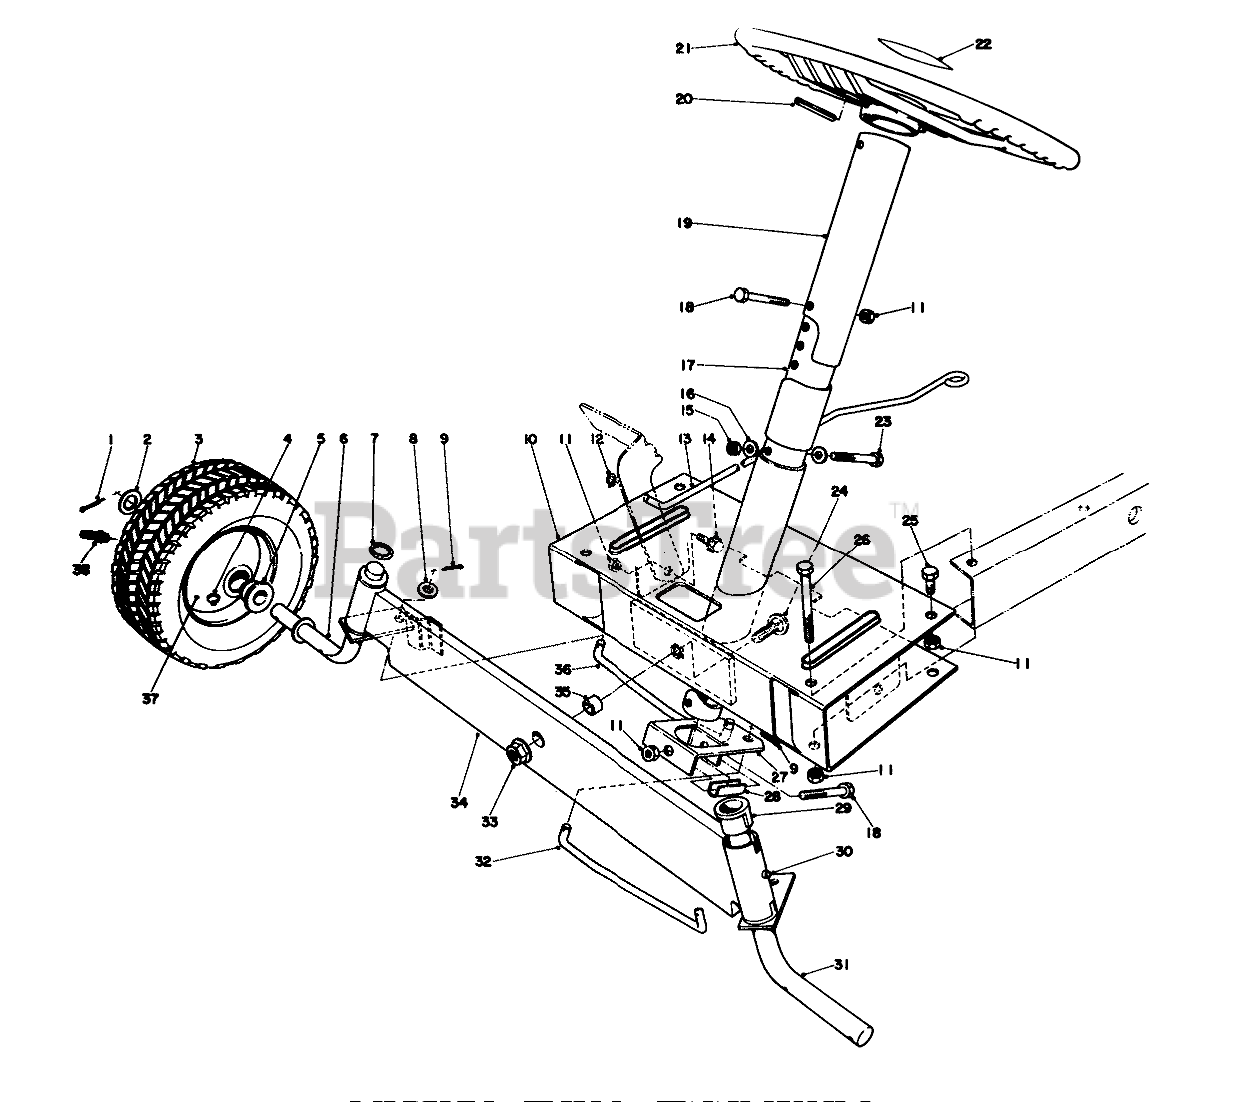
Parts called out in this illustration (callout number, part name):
1	PIN-COTTER
2	WASHER-FLAT
3	Tire Turf King
4	FITTING-GREASE
5	BUSHING
6	Spindle-R.H.
7	RING-RETAINING
8	WASHER-FLAT
9	PIN-COTTER
10	Front Frame
11	NUT-LOCK, CONE
12	Retaining Ring
13	Brake Rod
14	SCREW-SHOULDER
15	NUT-LOCK, CONE
16	WASHER-FLAT
17	Steering Tube Inner
18	SCREW-HH
19	Steering Tube Outer
20	PIN-ROLL
21	Steering Wheel
22	Decal
23	SCREW-HH
24	SCREW-CARR
25	SCREW-HH
26	SCREW-HH
27	Steering Lever
28	Spacer-Steering Tube
29	BUSHING
30	GREASE FITTING
31	Spindle, L.H.
32	Tie Rod-L.H.
33	NUT-HF
34	Front Axle
35	FRONT AXLE SPACER
36	Tie Rod-R.H.
38	STEM-VALVE
